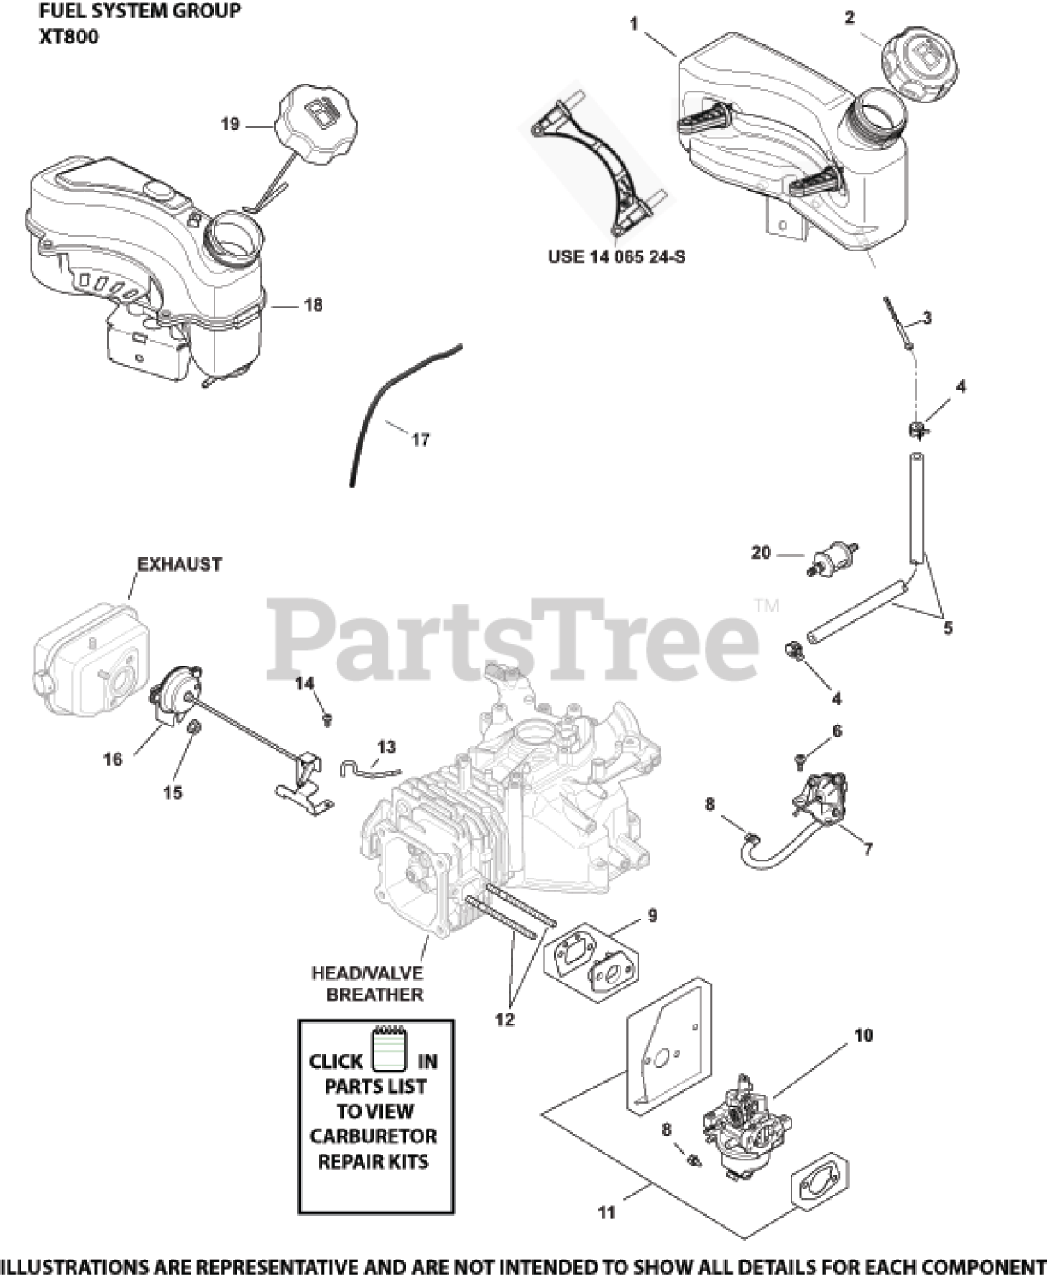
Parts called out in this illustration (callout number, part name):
3	FILTER, FUEL IN-NIPPLE
4	CLAMP, HOSE (NON-CALIFORNIA) - USE 14 237 10-S
5	HOSE, FUEL LOW-PERMEATION
9	KIT, SPACER
10	KIIT, CARBURETOR 13 MM STD CHOKE
11	KIT, CARBURETOR HEAT SHIELD GASKET
12	STUD,M6X1.0X100.2MM
17	HOSE, EVAPORATIVE
18	TANK, FUEL USE 14 065 63-S
19	CAP ASSEMBLY, FUEL
